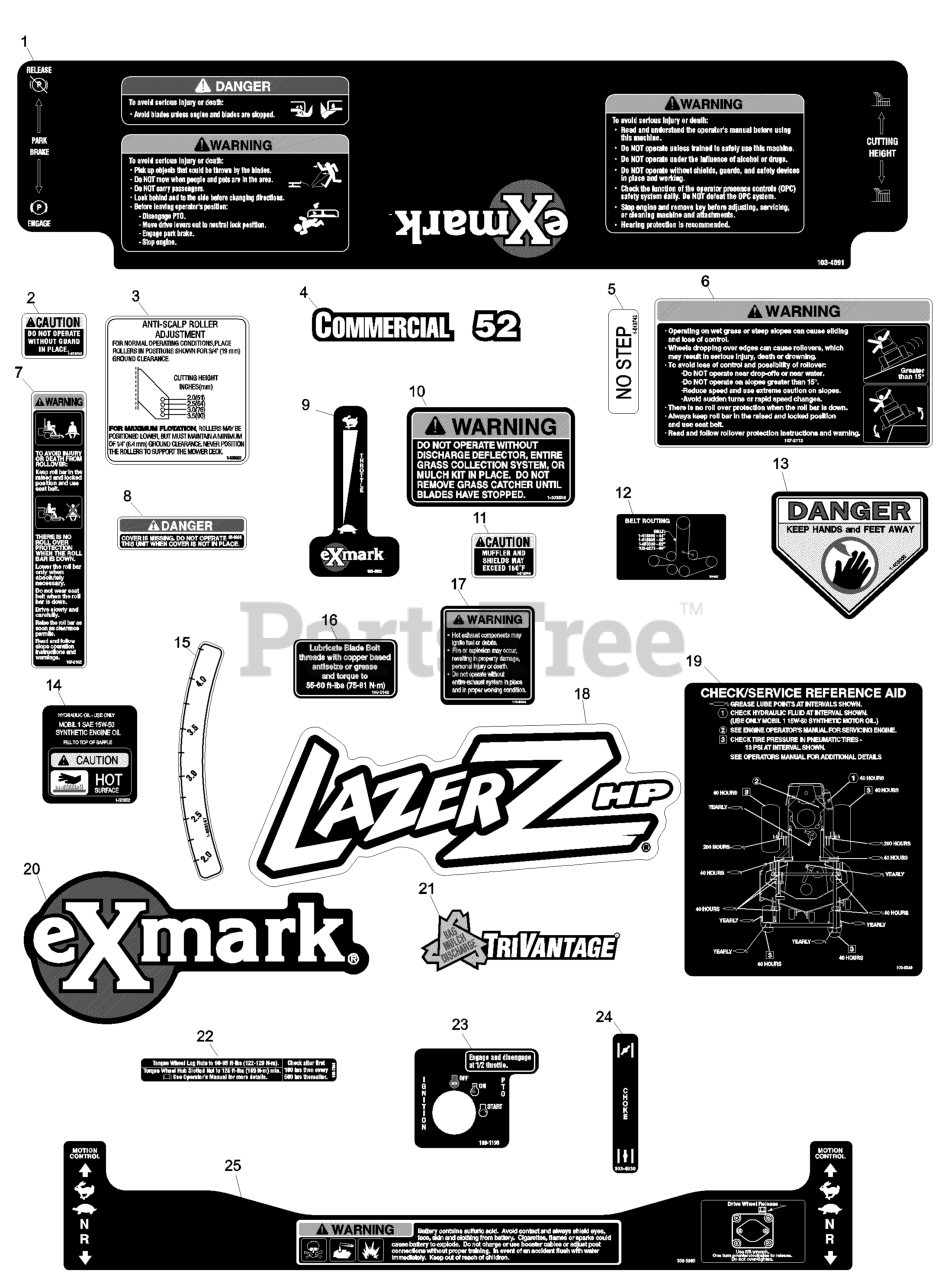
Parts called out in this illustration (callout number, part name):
1	DECAL,CONSOLE LHP
2	DECAL-GUARD
3	DECAL,ANTISCALP
4	DECAL,COMMERCIAL 52
5	DECAL,NO STEP
6	DECAL-WARNING
7	DECAL-WARNING, FOLDING RO
8	DECAL-COVER, MISSING
9	DECAL,THROTTLE
10	DECAL-WARNING, DISCHARGE
12	DECAL, BELT ROUTING
13	DECAL-DANGER
15	DECAL-DECK HEIGHT, INNER
16	DECAL,BOLT TORQUE
17	DECAL-EXHAUST
18	DECAL,LHP MODEL
19	DECAL,CHECK/SERVICE LHP
20	DECAL,EXMARK LOGO
23	DECAL,IGNITION/PTO
24	DECAL,CHOKE
25	DECAL-WARNING
